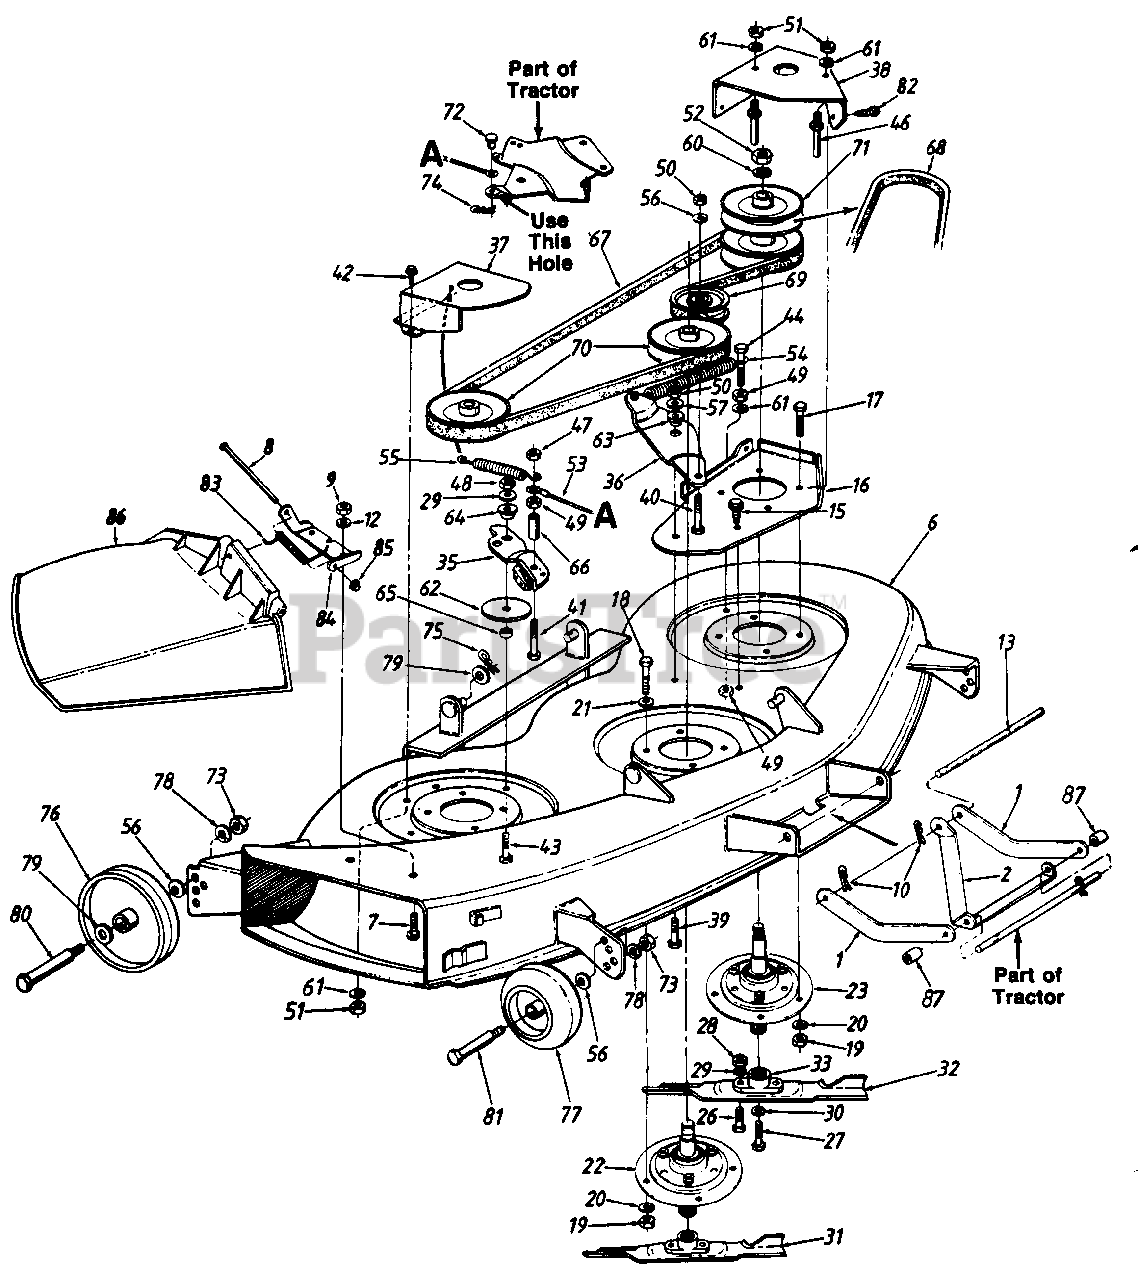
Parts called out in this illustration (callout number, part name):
7	Truss Mach. Scr. 20 x .75"
8	Hinge Pin
9	Hex Jam Nut 1/4-20 Thd.
12	Bell-Wash. 1/4 l.D.
13	Deck Connecting Rod
15	Hex TT-Tap Scr. 5/16-18 x .62"
18	Hex Bolt 5/16-24 x .75" Lg.
19	Hex Nut 5/16-24 Thd.
20	L-Wash. 5/16" I.D.
21	Bell-Wash. 5/16" I.D.
22	Spindle Ass'y.
23	Spindle Ass'y.
26	Hex Bolt 5/124 x 1.0" Lg.
27	Hex Cl-Bolt 3/8-24 x .88" Lg.
28	Hex Nut 5/16-24 Thd.
29	L-Wash. 5/16" l.D.
30	L-Wash. 3/8" l.D.-H.D.
31	High Lift Blade 14.88" Lg.
32	High Lift Blade 16.28" Lg.
33	Blade Adapter
35	Deck Brake Brkt. Ass'y.
36	Idler Bracket
40	Hex Bolt 3/8-24 x 1.5" Lg.
41	Hex Bolt 1/4-28 x 1.75" Lg.
42	Hex Wash. Hd. Tap-Scr. 1/-20 x .5" Lg.
43	Hex Bolt 5/16-24 x 1.25" Lg. (Grade 5)
44	Hex Bolt 1/4-28 x 1.5" Lg.
46	Belt Guard Pin 1/ 4 Dia.
47	Hex Cent. L-Nut 1/4-28 Thd.
48	Hex Nut 5/16-24 Thd.
49	Hex Nut 1/4-28 Thd.
50	Hex Nut 3/8-24 Thd.
51	Hex Nut 1/4-20 Thd.
52	Hex Jam Nut 5/8-18 Thd.
53	Brake Cable Ass'y.
54	Extension Spring 6.17" Lg.
55	Extension Spring 3.97 Lg.
56	Bell-Wash. .38" I.D. x .88" O.D.
57	Bell-Wash. .39 I.D. x 1.13" O.D.
60	Bell-Wash. 5/8 I.D. x 1.25" O.D.
61	L-Wash. l/4 I.D.
62	Fl-Wash. 5/16" I.D. x 3" O.D.
63	Shld. Spacer .625" l.D.
64	Shld. Spacer
65	Spacer.34" I.D.
66	Spacer.326" l.D.
67	V-Belt
68	V-Belt
69	Fl-ldler w/Flanges 3.5" O.D.
70	Pulley Son Dia.
71	Pulley S.on Dia.
72	Clevis Pin 1/4" Dia. x .53n
73	Hex Nut 3/8-16 Thd.
74	Intern. Cotter Pin 5/16" Dia.
75	Intern. Cotter Pin 3/8 Dia.
76	Deck Wheel 5" Dia.
77	Deck Wheel w/lnsert 5" Dia.
78	L-Wash. 3/8" l.D.
79	Fl-Wash..531" l.D.
80	Shoulder Bolt .498" Dia. x 1.64" Lq.
81	Shoulder Bolt
82	Hex Wash. Hd. Tap-Scr. 1/4-20 x 38" Lg.
83	Torsion Spring
84	Hinge Mtg. Brkt.
86	Chute Ass'y. Comp.
87	Spacer 5/8" l.D. x 7/8" O.D.
